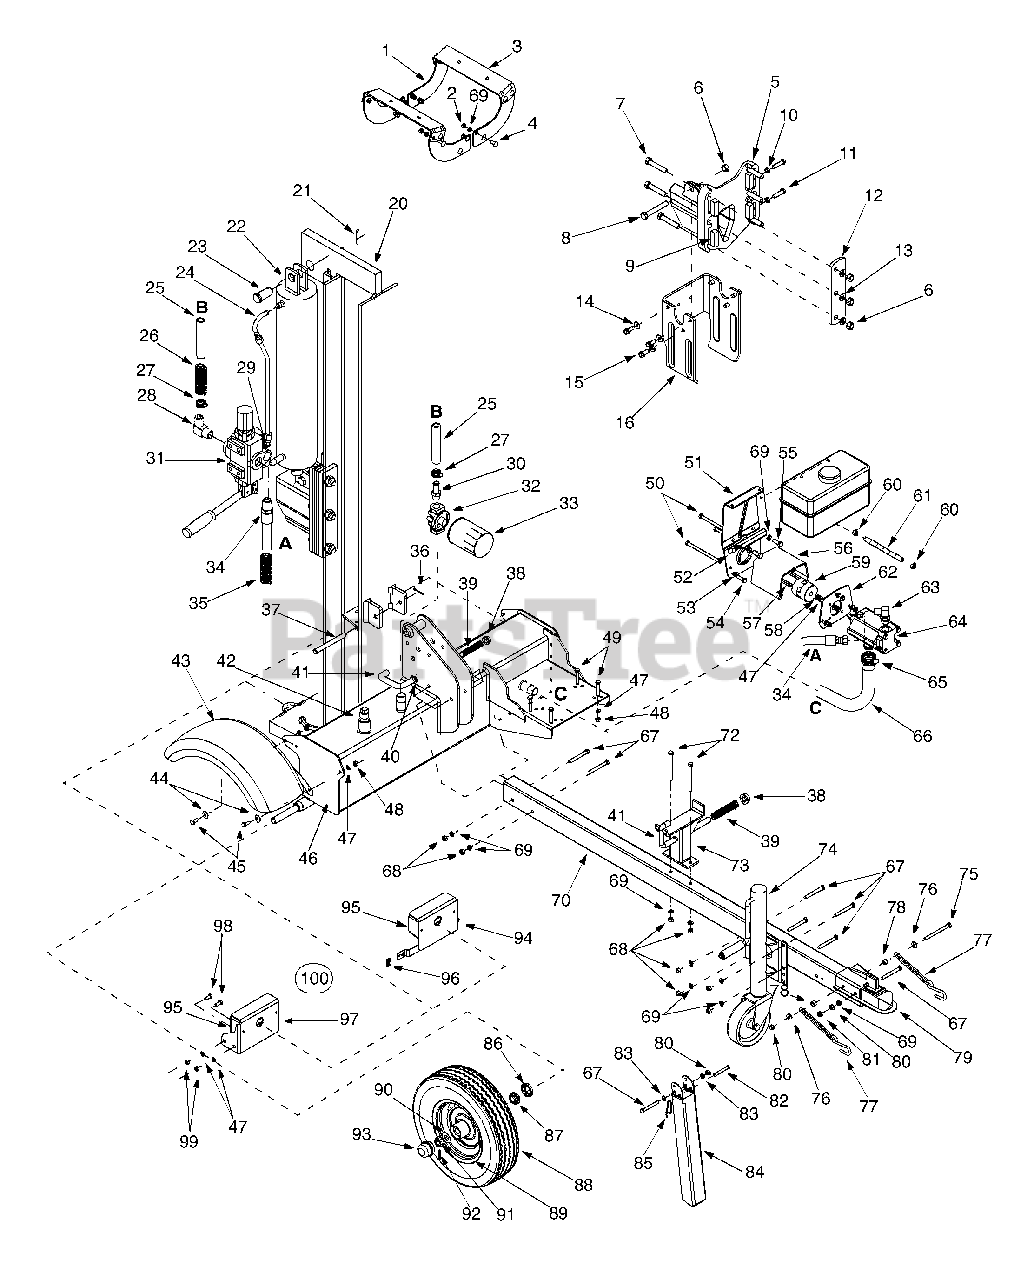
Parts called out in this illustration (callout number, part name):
4	Carriage Bolt 3/8-16 x 1.0
5	Wedge Assembly
6	Lock Nut 1/2-20
7	Hex Cap Screw 1/2-20 x 2.75
8	Hex Cap Screw 1/2-20 x 3.50
10	Hex Jam Nut 3/8-24
11	Hex Cap Screw 3/8-24 x 1.5
13	Lock Washer 1/2
14	Flat Washer .406 ID x .875 OD
15	Hex Washer Screw 3/8-16 x 1.
20	Beam Assembly
21	Cotter Pin
22	Kit Seal 5.0" for Best Metals cylinder 718-0313
22	Hydraulic Cylinder
22	Kit Seal 5.0" for XINGHUI cylinder 718-0313A
22	Kit Seal 5.0" for ENERGY cylinder 718-0313A
23	Clevis Pin
24	Hydraulic Tube
25	Return Hose 3/4" ID x 44" Lg.
26	Hose Guard
27	Hose Clamp 5/8"
28	Return Elbow
29	90 Degree Solid Male Adapter
30	3/4" Hose Adapter
32	Filter Housing
33	Oil Filter
34	High Pressure Hydraulic Hose
35	Hose Guard
36	Cotter Pin 1/8"
37	Hinge Pin 1/2 x 4.8" Lg.
38	Push Cap
39	Compression Spring 4"
40	Flat Washer .635 ID x .93 OD
41	Locking Rod
42	Vented Dipstick
45	Hex Cap Screw 5/16-24 x .75
46	Frame Assembly 7.0 Gal
47	Lock Washer 5/16
48	Hex Nut 5/16-24
49	Hex Cap Screw 5/16-24 x 1.75
50	Hex Cap Screw 5/16-24 x 5.25
51	Fuel Tank Mounting Bracket
52	Fuel Tank Mounting Bracket
53	Lock Washer 3/8
54	Hex Cap Screw 5/16-24 x 1.0
55	Hex Cap Screw 3/8-16 x 1.0
56	Shoulder Spacer
57	Key 1/4" x 2.00"
57	Key 3/16" x .75"
58	Hex Screw 5/16
59	Flexible Coupling 1.00 x .437
60	Hose Clamp
61	Fuel Line Hose
63	Adapter 7/8-14
64	Gear Pump (16 gmp)
64	Pump Kit
64	Gear Pump (15 gpm)
65	Hose Clamp
66	Suction Hose
67	Hex Cap Screw 3/8-16 x 3.0
68	Hex Nut 3/8-16
69	Lock Washer 3/8
72	Hex Cap Screw 3/8-16 x 4.0
75	Hex Cap Screw 3/8-16 x 4.25
76	Flat Washer .385 ID x .870 OD
77	Chain
78	Spacer
79	Hitch Coupler
80	Lock Nut 3/8-16
81	Hex Jam Nut 3/8-16
82	Clevis Pin
83	Flat Washer
86	Bearing Seal
87	Bearing Cone
88	Wheel Assembly
89	Rim Assembly - Gray
90	Flat Washer .76" ID x 1.5" OD
91	Slotted Nut 3/4-16
92	Cotter Pin 5/32" x 1-1/4" Lg.
93	Hub Cap
96	Nut 1/4-20
99	Hex Nut 5/16-24
100	Taillight Kit
